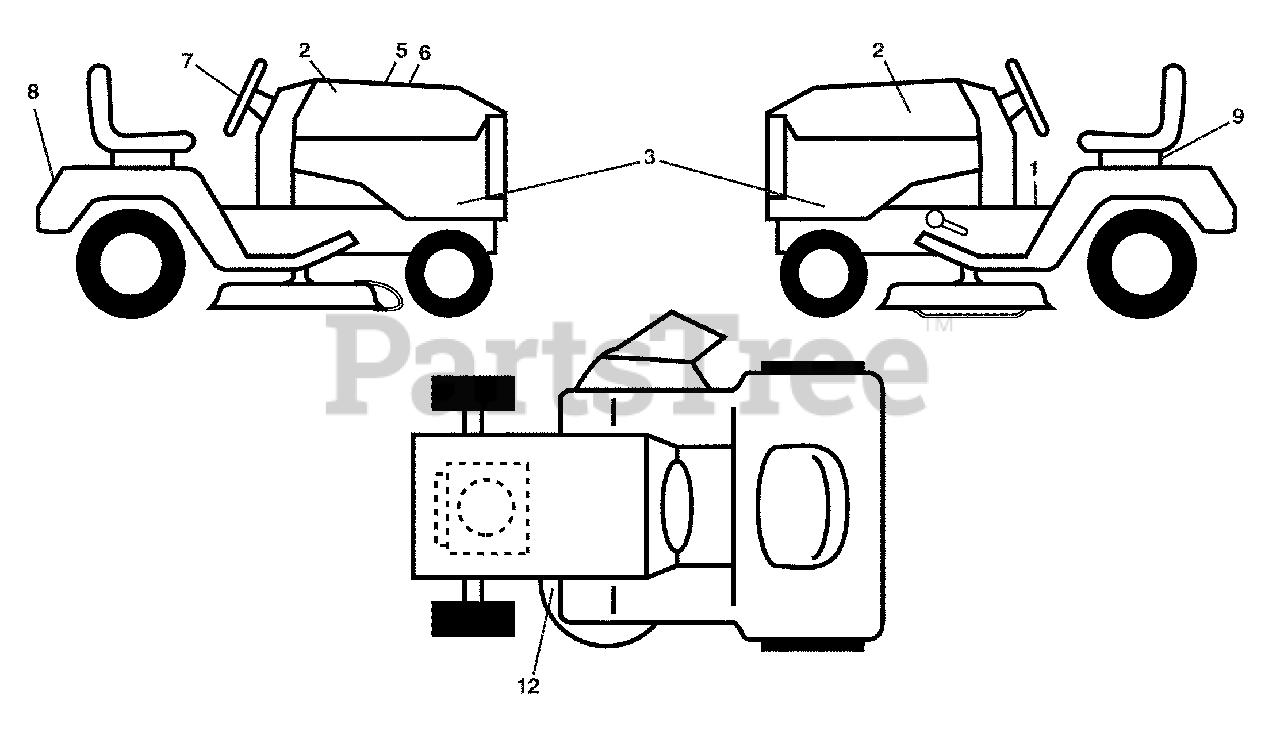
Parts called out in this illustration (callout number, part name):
1	Decal, Fender Warning
2	Decal, Hood
3	Decal, Hood Panel SD
5	Decal, Customer Respons.
6	Decal, Replacement
7	Decal, Steering Wheel
8	Decal, Fender
9	Decal, Battery Dnge/Poi
12	Decal, Mower V-Belt Schematic
